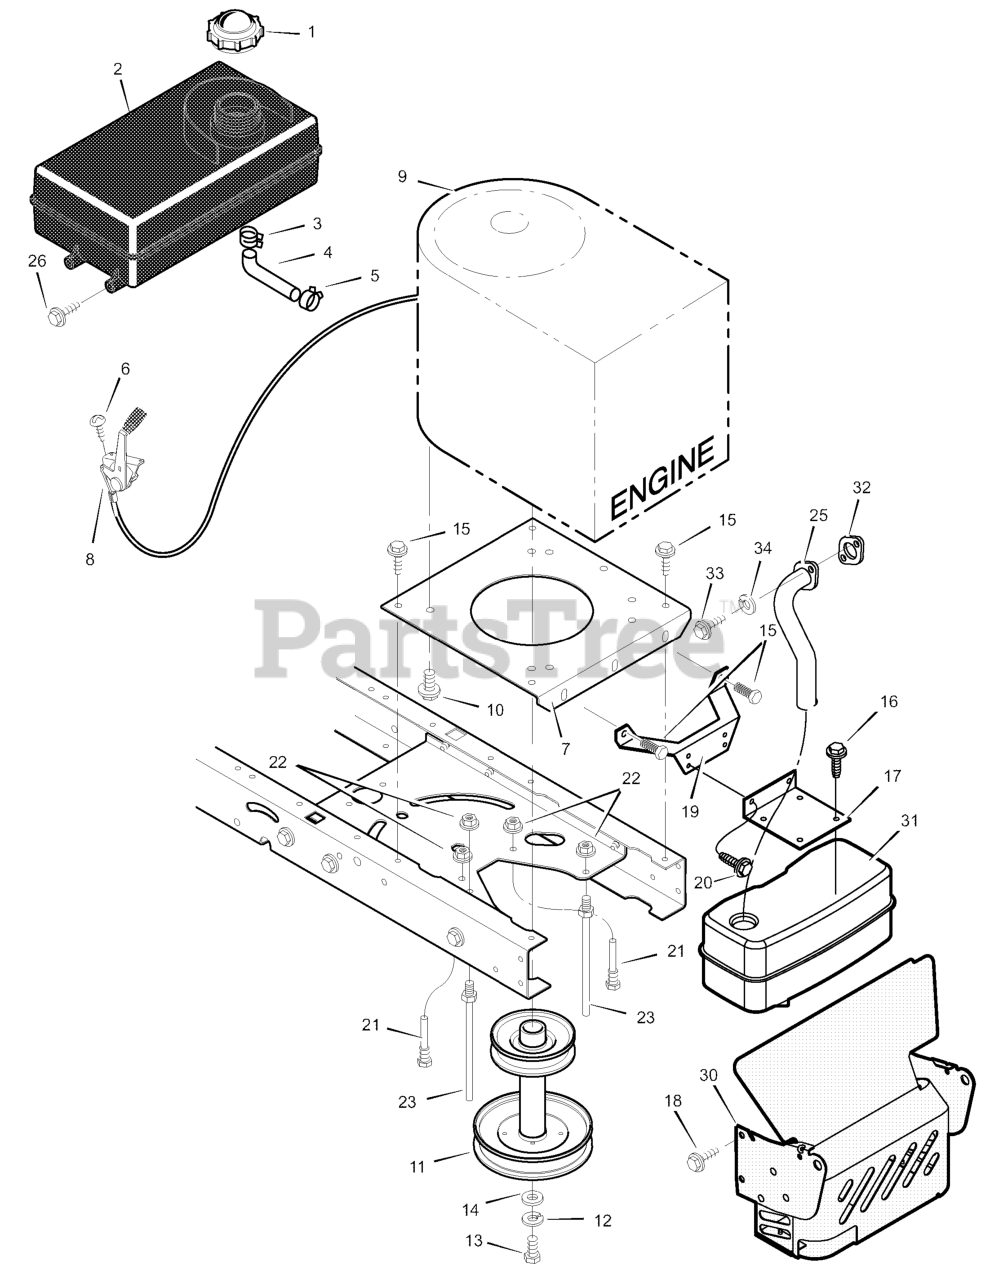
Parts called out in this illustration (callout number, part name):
1	Fuel Cap
2	TANK, Fuel 1.4 Gal.
3	Hose Clamp
4	Fuel Line (Must cut to length)
5	Hose Clamp
7	Plate, Engine
8	Throttle Control
9	Engine
10	Bolt, Engine Mount
11	STACK PULLEY ASSEMBLY
12	Lockwasher
13	Bolt, Hex
17	Bracket, Muffler
19	Bracket, Muffler Mount
21	Guide, Belt
22	Nut, Flange
23	Guide, Belt
25	Exhaust Tube, Single
30	SHIELD, Heat
31	Muffler
32	GASKET, Exhaust
34	Washer
